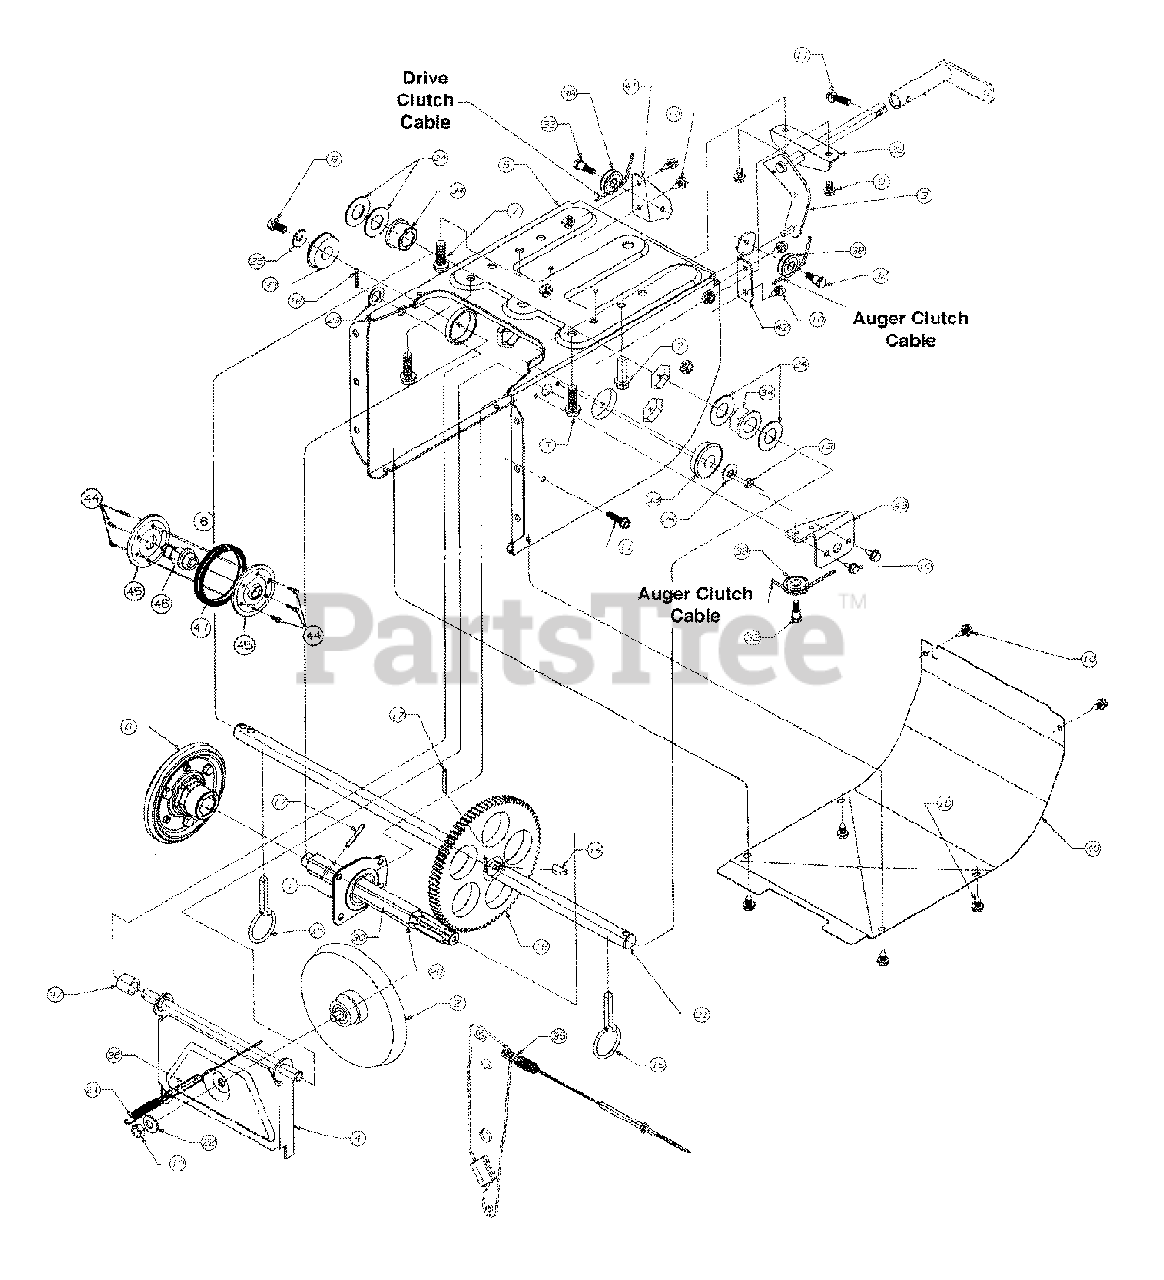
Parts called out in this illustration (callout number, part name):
1	Bearing Ass'y.
2	Ass'y., Friction Wheel Disc
3	Rod Shift, Wheel Drive
4	Brkt. Ass'y. Friction Wheel
5	Frame Ass'y., 600 S/T
6	Wheel Friction
7	Hex Self-Tap Screw
8	Hex, Bolt 5/16-18 x .62
9	Scr., Hex Wash. Hd., TT 1/4-20 x .5"
10	Hex Self-Tap Scr.
11	Screw, Hex
13	Nut, Hex
14	Key
15	Pin, Klick
16	Pin, Cotter
17	Pin, Roll
20	Shaft, Hex
21	Extension Spring
22	Washer, Bell
23	Flat Washer
24	Washer, Flat
25	Washer, Bell
30	Lubricant
31	Axle
32	Screw, Shoulder
33	Bearing, Ball
34	Flange Bearing
35	Cable, Auger
36	Cable, Clutch
37	Spacer
38	Roller, Cable
40	Cover, Frame
41	Bracket, Drive Cable Roller
42	Brkt., Auger Clutch Cable Guide
43	Brkt., Front Support Guide
44	Hex Wash Hd. TT-Tap Scr. 1/4-20 x .5" Lg.
45	Friction Plate
46	Friction Wheel Hub
47	Friction Wheel Rubber
